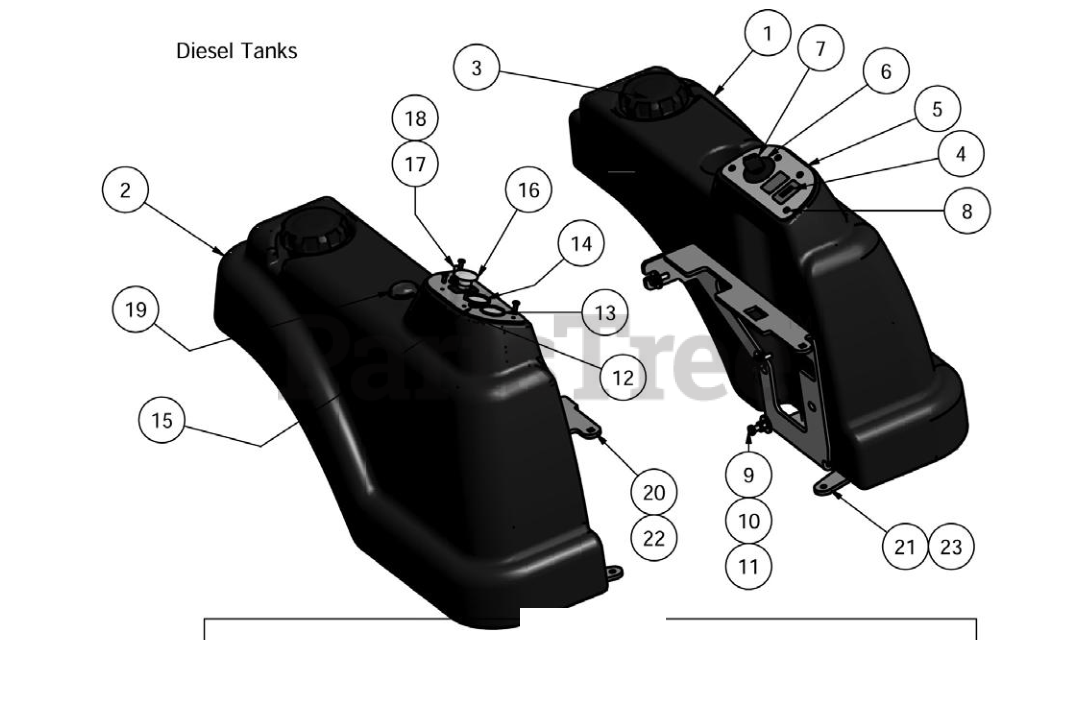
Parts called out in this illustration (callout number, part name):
1	Left Fuel Tank
2	Right Fuel Tank
3	Diesel Fuel Cap
4	Hourmeter-Diesel
5	Control Panel (Left)
6	Ignition Switch
7	Ignition Key
8	10mm x 32 x 1" Bolt
9	5/16" x 1" Hex Bolt
10	5/16" Lock Washer
11	5/16" Flat Washer
12	Diesel Control Panel (Right)
13	Oil Gauge with Sender
14	Temperature Gauge with Sender
16	PTO Engager
17	Deck Lift Joystick
18	Joystick Cover
19	Fuel Gauge and Grommet
20	Tank Support-Left (60")
21	Tank Support-Right (60")
22	Tank Support-Left (72")
23	Tank Support-Right (72")
